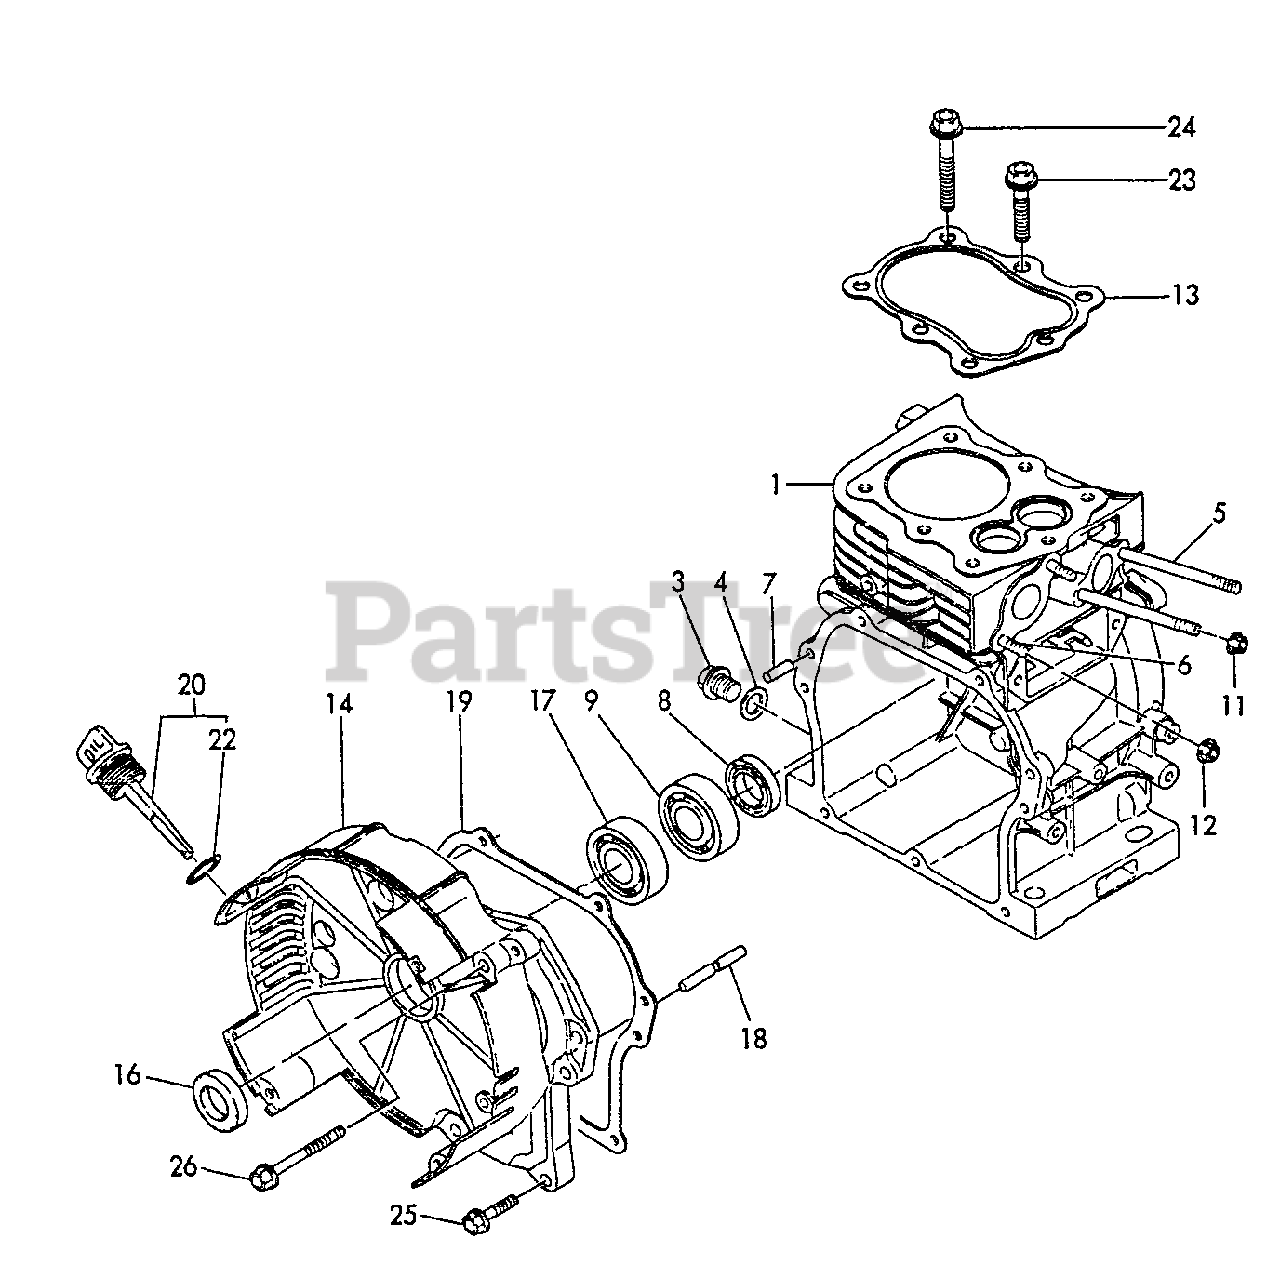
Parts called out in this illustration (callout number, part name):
1	CYLINDER BLOCK SET
3	PLUG, DRAIN
4	GASKET
5	BOLT - 6X70
6	BOLT - 6X16
7	PIN - 6X16
8	SEAL, OIL
9	BEARING, BALL - 6204C3
11	NUT - 6 -- FLANGE
12	NUT - 6 -- FLANGE
13	GASKET, CYLINDER
14	SIDE COVER ASSY
16	SEAL, OIL
17	BEARING, BALL - 6204C3
18	SHAFT, GOVERNOR
19	GASKET
20	CAP ASSY
22	O-RING - 18
23	BOLT - 8X39
24	BOLT - 8X60
25	BOLT - 6X25
26	BOLT - 6X55
